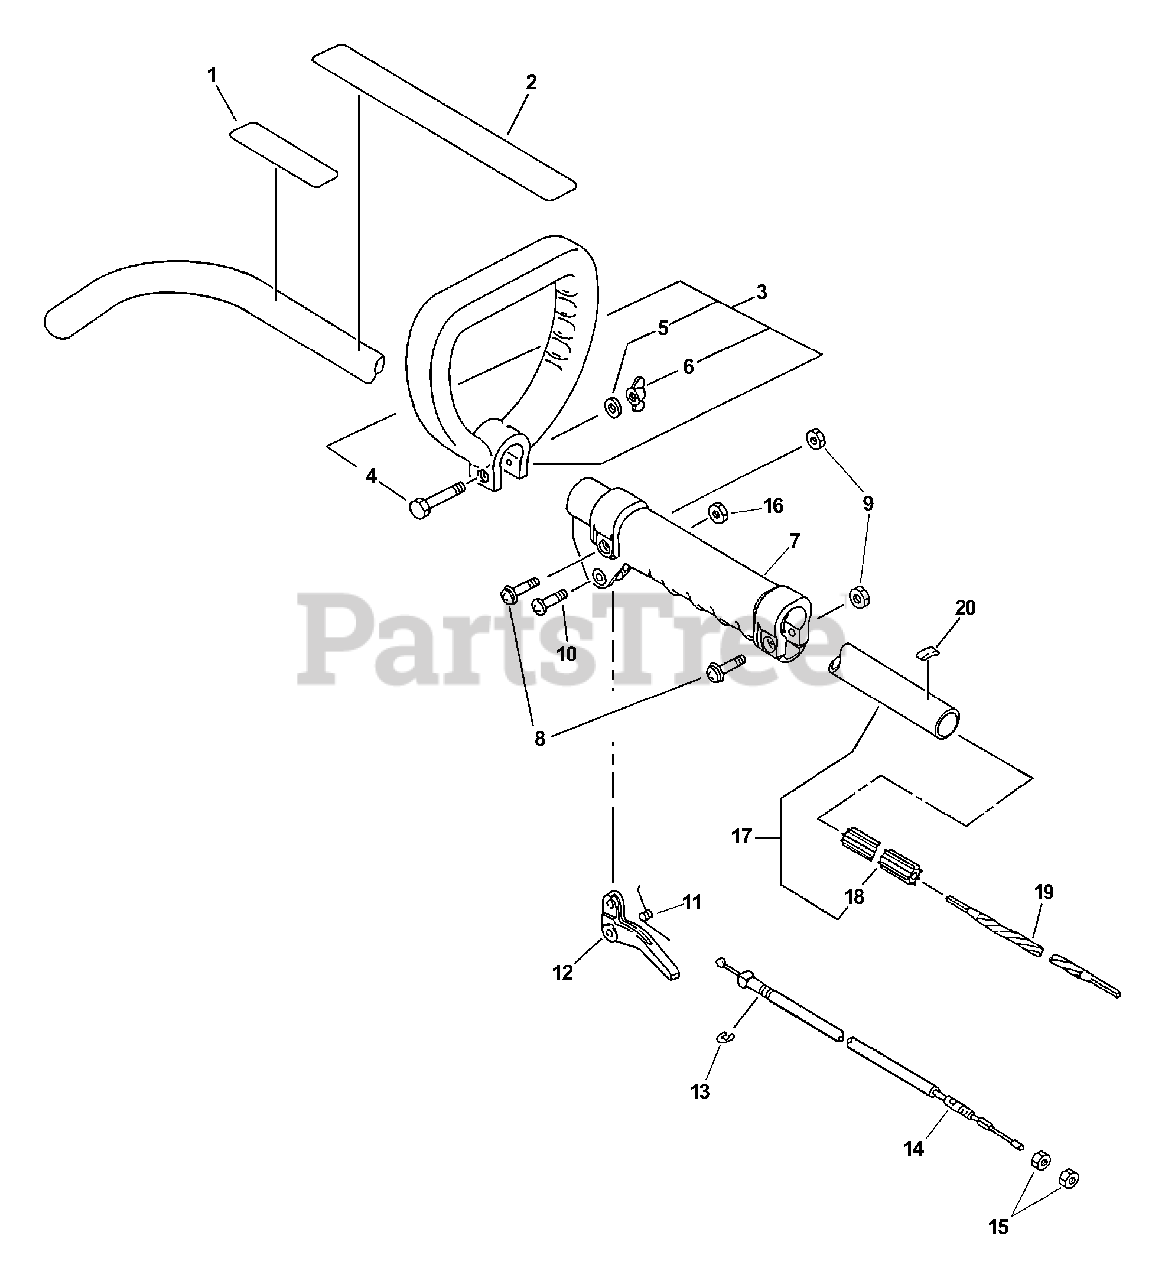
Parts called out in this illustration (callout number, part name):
1	LABEL - CAUTION -- SPANISH
2	LABEL - CAUTION
3	HANDLE ASSY - FRONT
4	BOLT - 1/4-20 X 1-1/2"
5	WASHER - 1/4"
6	WINGNUT - 1/4-20
7	GRIP, HANDLE
8	SCREW - 5X25
10	SCREW - 5X30
11	SPRING, TRIGGER
12	TRIGGER, THROTTLE
13	RING, RETAINING - 5
14	CABLE, THROTTLE
16	LOCKNUT - 5
17	MAIN PIPE ASSY
18	LINER - FLEXIBLE
19	DRIVESHAFT - FLEXIBLE
20	LABEL - ALIGNMENT
